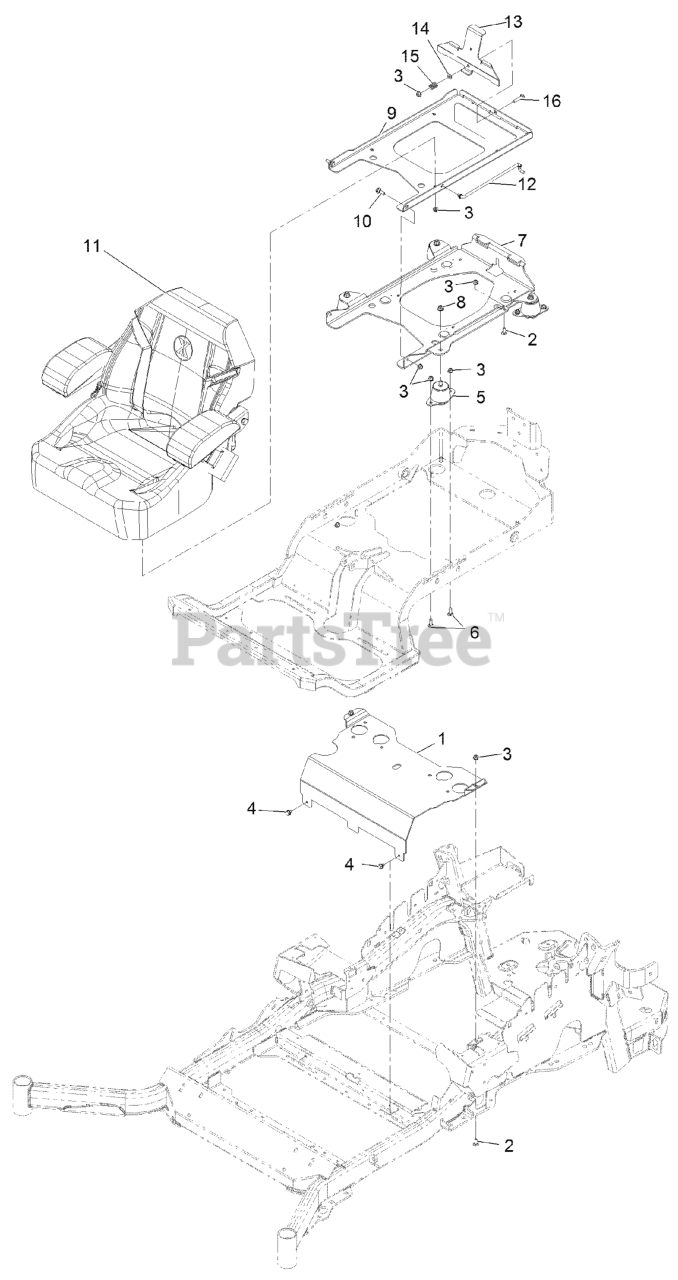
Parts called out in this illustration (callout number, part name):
1	Panel-Front, Seat Mount
2	SCREW-CARR
3	NUT-HF, NI
5	ISOLATOR-SEAT
6	BOLT-CARR
7	PLATE-SUPPORT, ISO SEAT
8	NUT-HF, NI
9	PLATE-FRAME, SEAT
10	SCREW-SHOULDER
11	SEAT-EXMARK STANDARD
12	ROD-PROP
13	PLATE-LATCH,SEAT
14	WASHER-PLAIN
15	SPRING-COMPRESSION
16	BOLT-CARR
